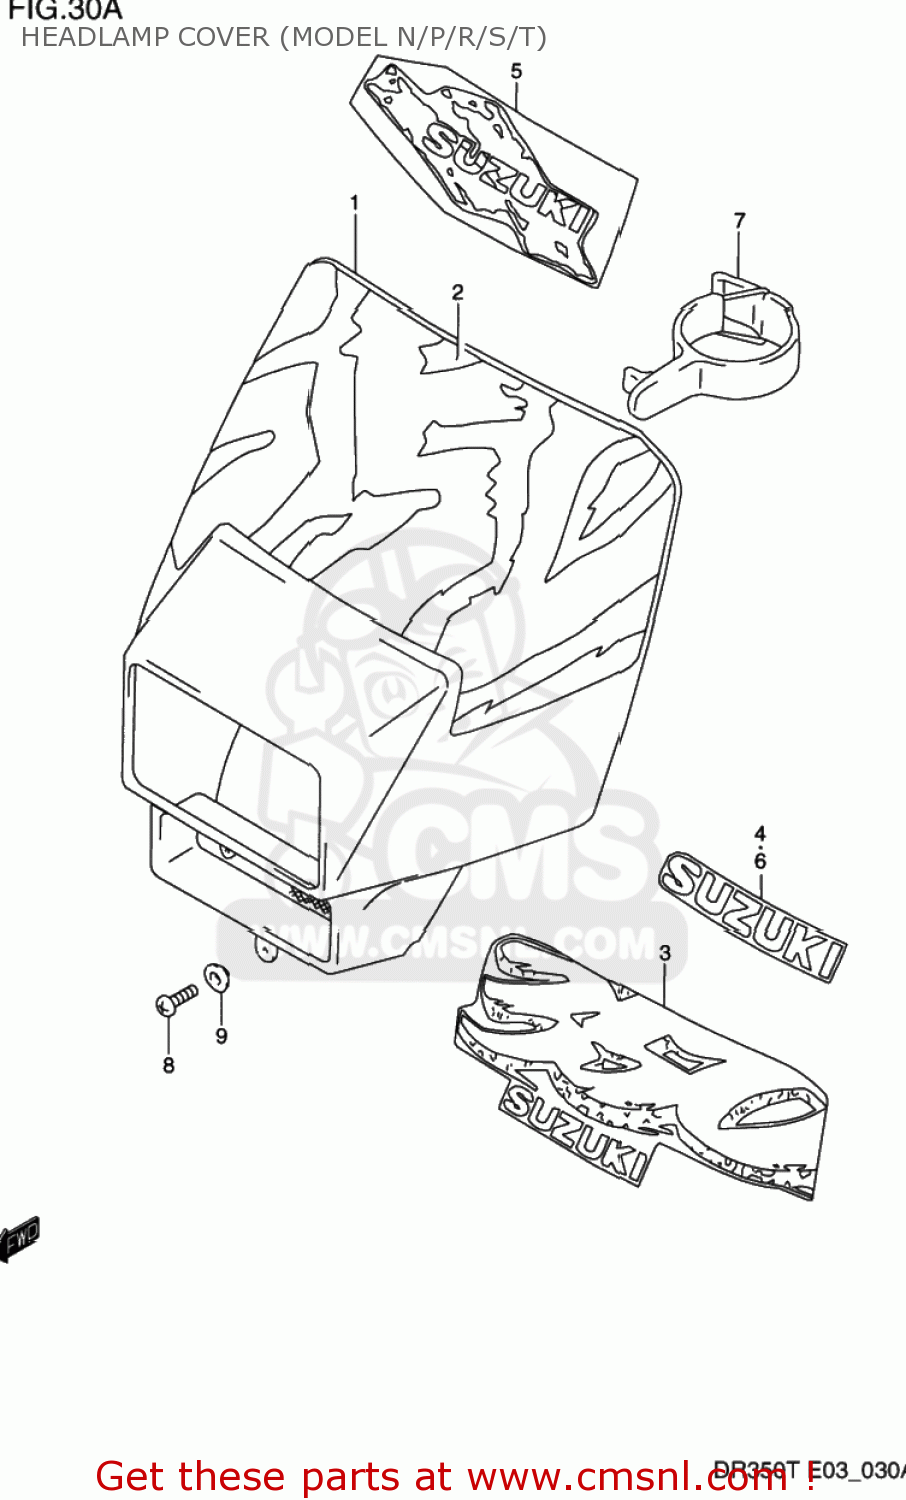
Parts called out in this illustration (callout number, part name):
1	COVER,HEADLAMP
2	TAPE,HEADLAMP COVER
3	EMBLEM.HEADLAMP
4	EMBLEM,HEADLAMP COVER
5	TAPE,HEADLAMP COVER
6	EMBLEM,SUZUKI
7	BAND,HEADLAMP COVER
8	SCREW(5X12)
9	WASHER
